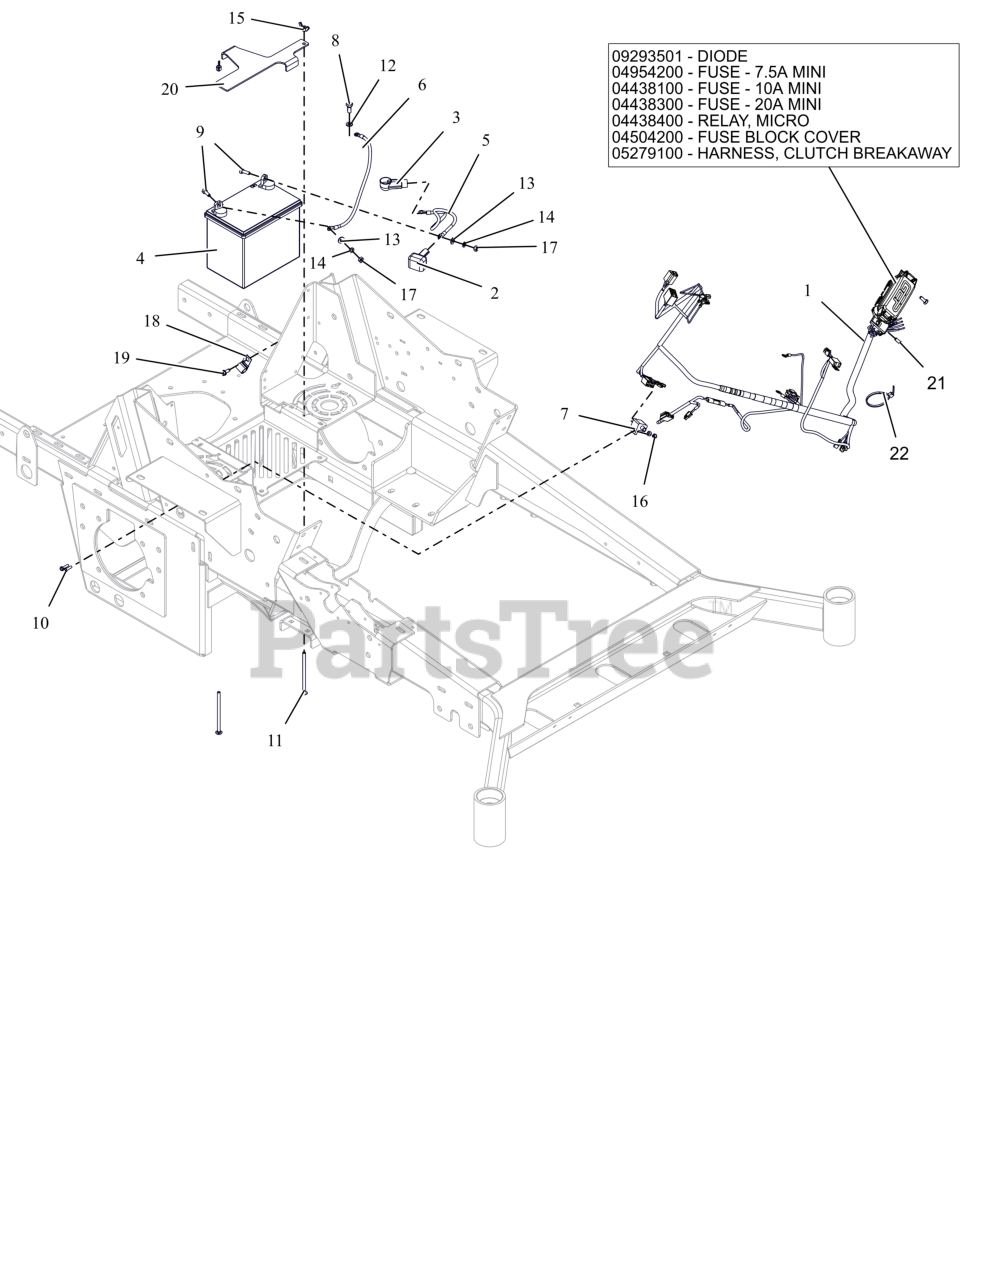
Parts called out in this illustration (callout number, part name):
1	HARNESS- WIRE PT300 MAIN
1	DIODE, CONNECTOR SHELL
1	FUSE, 7.5 AMP MINI-ATC
1	FUSE,10 AMP MINI-ATC
1	FUSE,20 AMP MINI ATC
1	RELAY,MICRO5 TERML W/RESISTOR
1	COVER, HARNESS FUSE/RELAY MOD
1	HARNESS, CLUTCH BREAKAWAY
2	INSULATOR
3	BOOT, .65ID POS
4	BATTERY, 300 CCA 10U1L
5	CABLE, STARTER 13.00"
6	CABLE-GROUND .25 X 13.00 X .31
7	SWITCH- DOUBLE POLE N.O./N.O.
8	BLT, HEX M8-1.25X20 G8.8 ZCC
9	BLT, HEX .25-20X.75 G5 ZCC
10	BLT, HWH #10-24X.75 ZCC
11	BLT, RHSN .25-20X4.50 G5 ZCC
12	WSHR,LK-REG .312X.078 ZCC
13	WSHR,FLT .281X.625X.065 ZCC
14	WSHR,LK-REG .250X.062 ZCC
15	NUT, LK-WING .25-20 ZCC
16	NUT-LK-NYL #10-24 G2 ZCC
17	NUT-STD .250-20 G2 ZCC
19	SCR,TAP .25-20X.625 HWH ZCC
20	HOLDDOWN- BATTERY
21	BLT, HEX M6-1X16 G8.8 ZCC
22	CABLE TIE, .15 X 8.50
